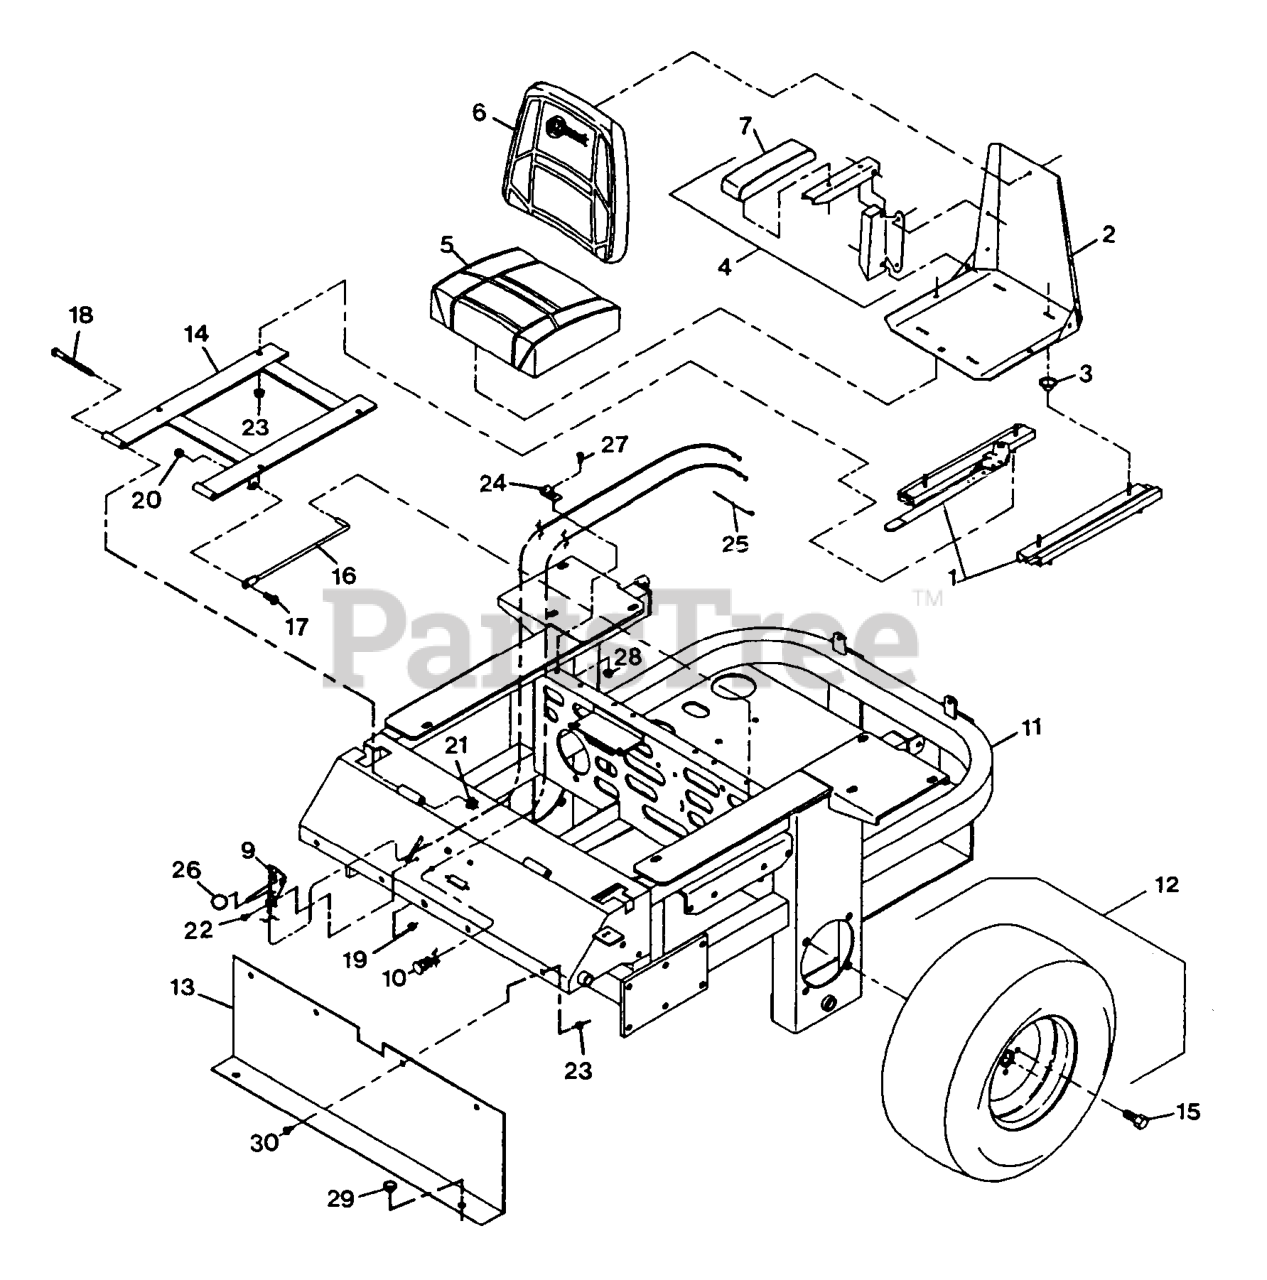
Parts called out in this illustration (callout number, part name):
3	SPACER-TRACK
10	CONTROL-CHOKE
15	WHEEL BOLT
16	ROD-HOLDUP, SEAT
22	BOLT-CARR
24	CLIP-LOOM
25	TIE-PLASTIC
26	KNOB-BALL
